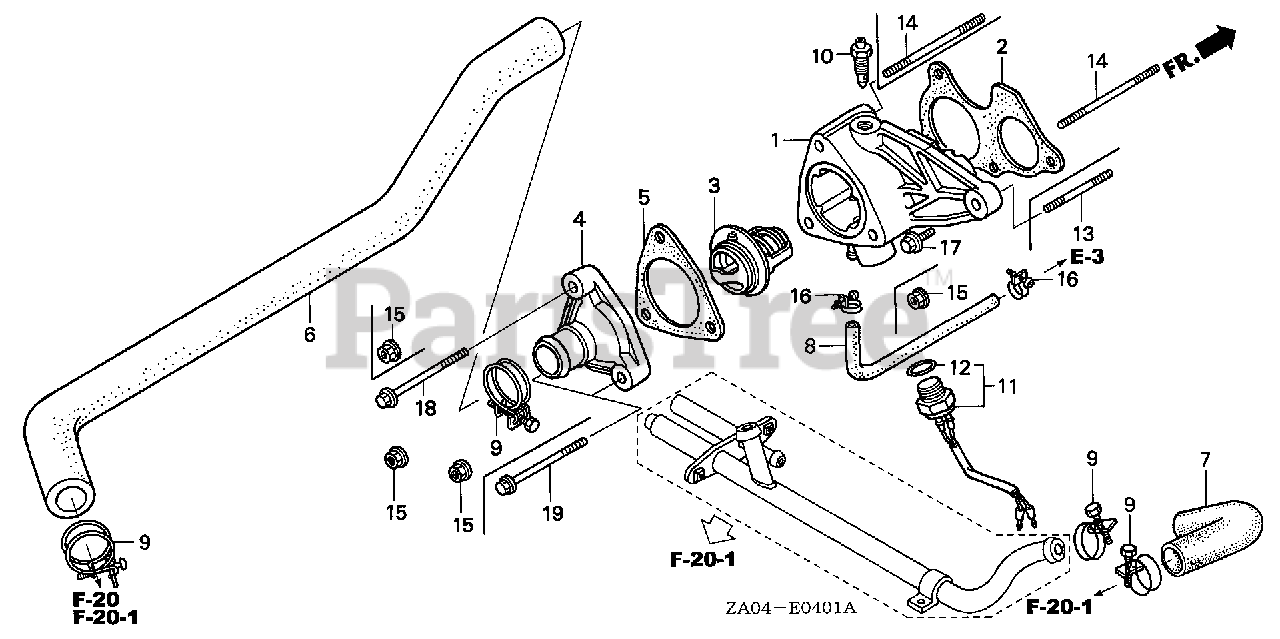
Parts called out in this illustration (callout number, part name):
1	CASE, THERMOSTAT
2	GASKET, GOVERNOR CASE
3	THERMOSTAT ASSY.
4	COVER, THERMOSTAT
5	GASKET, THERMOSTAT COVER
6	HOSE, WATER (UPPER)
8	HOSE, WATER BYPASS
9	CLIP, WATER HOSE
10	BOLT, BREATHING WATER
11	SWITCH, SOLENOID THERMOSTAT
12	O-RING (15.5X1.4)
13	BOLT, STUD (6X25)
14	BOLT, STUD (6X60)
15	NUT, FLANGE (6MM)
16	CLIP, TUBE (A13)
19	BOLT, FLANGE (6X60)
